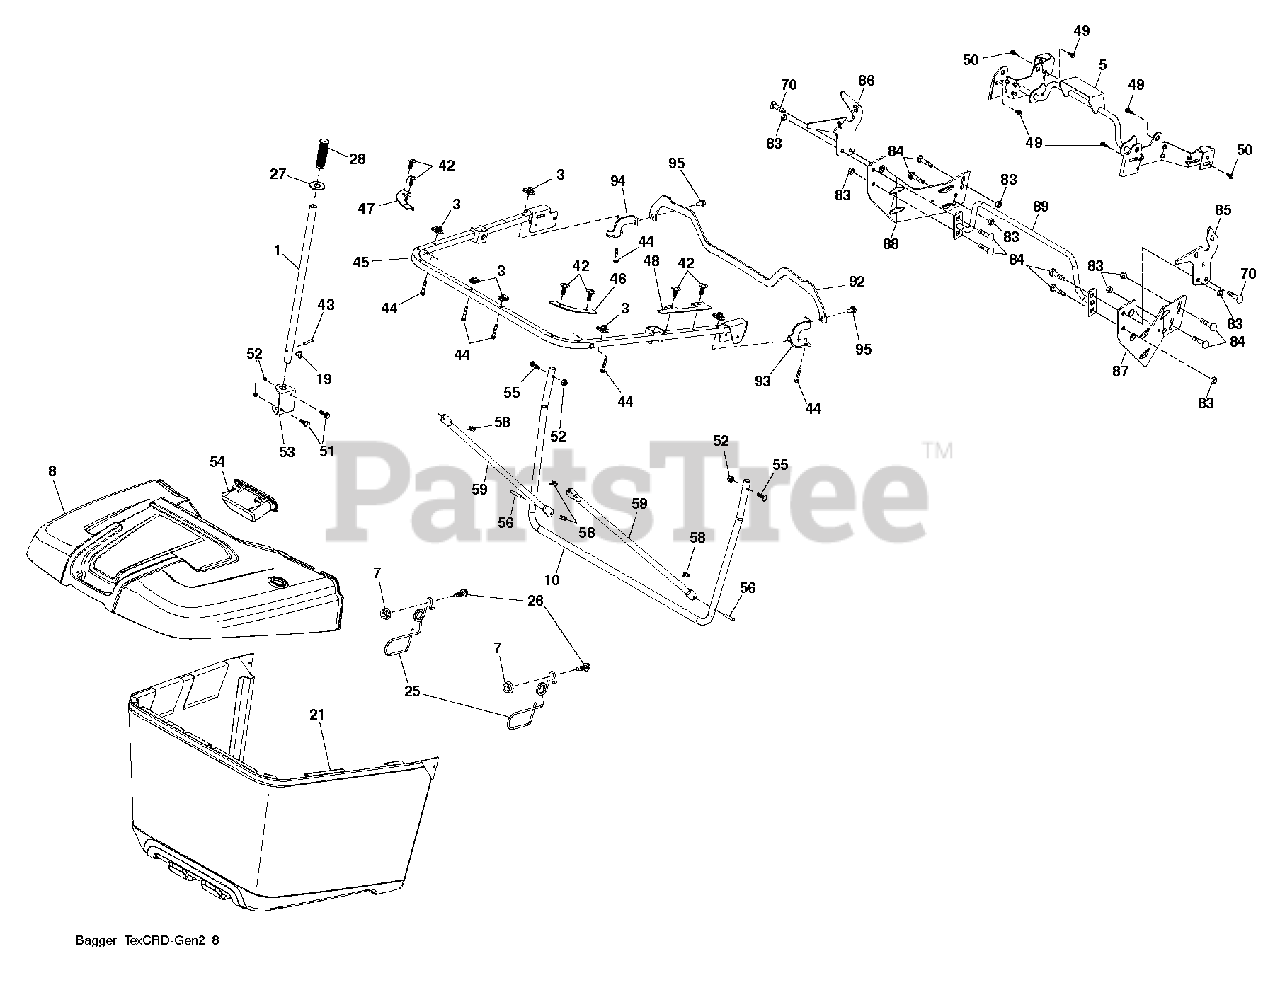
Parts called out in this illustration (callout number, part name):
1	TUBE.HANDLE.BAGGER.CRD/SRD.BLA
3	1/4-20 U NUT
5	FRAME TEX_CRD_GEN2 UPPER PIVOT
7	NUT T
8	COVER.BAG.NO_APP.CRD.GENII.498
10	FRAME TEX_CRD_GEN2 BAGGER FRAM
19	PIN.COTTER.5/16.BOW TI
21	BAG FRAME BAGGER ASSEMBLY. HUS
25	LATCH LATCH. BAG. CRD GEN 2
26	SCREW HEX CRT
27	GROMMET RUBBER GROMMET, DUMP T
28	GRIP.HANDLE.BLACK
42	CLIP CHRISTMAS TREE CLIP
43	RIVET,DRILLED
45	FRAME TEX_CRD_GEN2 UPPER U FRA
46	CONNECTOR RIGHT BAGGER CORNER
47	CONNECTOR LEFT BAGGER CORNER C
48	BAFFLE BAGGER SIDE CLOSE-OUT
49	BOLT, SHOULDER 5/16-18
50	BOLT, 5/16-18 X 1 3/4
51	BOLT.CARR.SQNK.5/16-18UNC.X3/4
52	NUT.71038.31-18.HEX.NYLOCK
53	BRACKET DUMP HANDLE BRACKET, T
54	HANDLE BAGGER TOP FRONT HANDLE
55	BOLT
56	PIN.CLEVIS.183
58	RETAINER CLIP PM
59	TUBE BAGGER SPREADER TUBE, TEX
70	SCREW, 3/8-16X3/4
83	NUT
84	BOLT D
85	BRACKET.RH.PIVOT.MAN.DUMP.BLAC
86	BRACKET.LH.PIVOT.MAN.DUMP.BLAC
87	BRACKET.RH.MID.SUP.BAG.TEX.CRD
88	BRACKET.LH.MID.SUP.BAG.TEX.CRD
89	TUBE.WELD.OFSET.STRUT.BAG.X431
92	BRACKET.PNT.BAGGER.TOP.SUPPORT
93	BRACKET.PNT.RH.SUPPORT.ATTACH
94	BRACKET.PNT.LH.SUPPORT.ATTACH
95	SCREW
